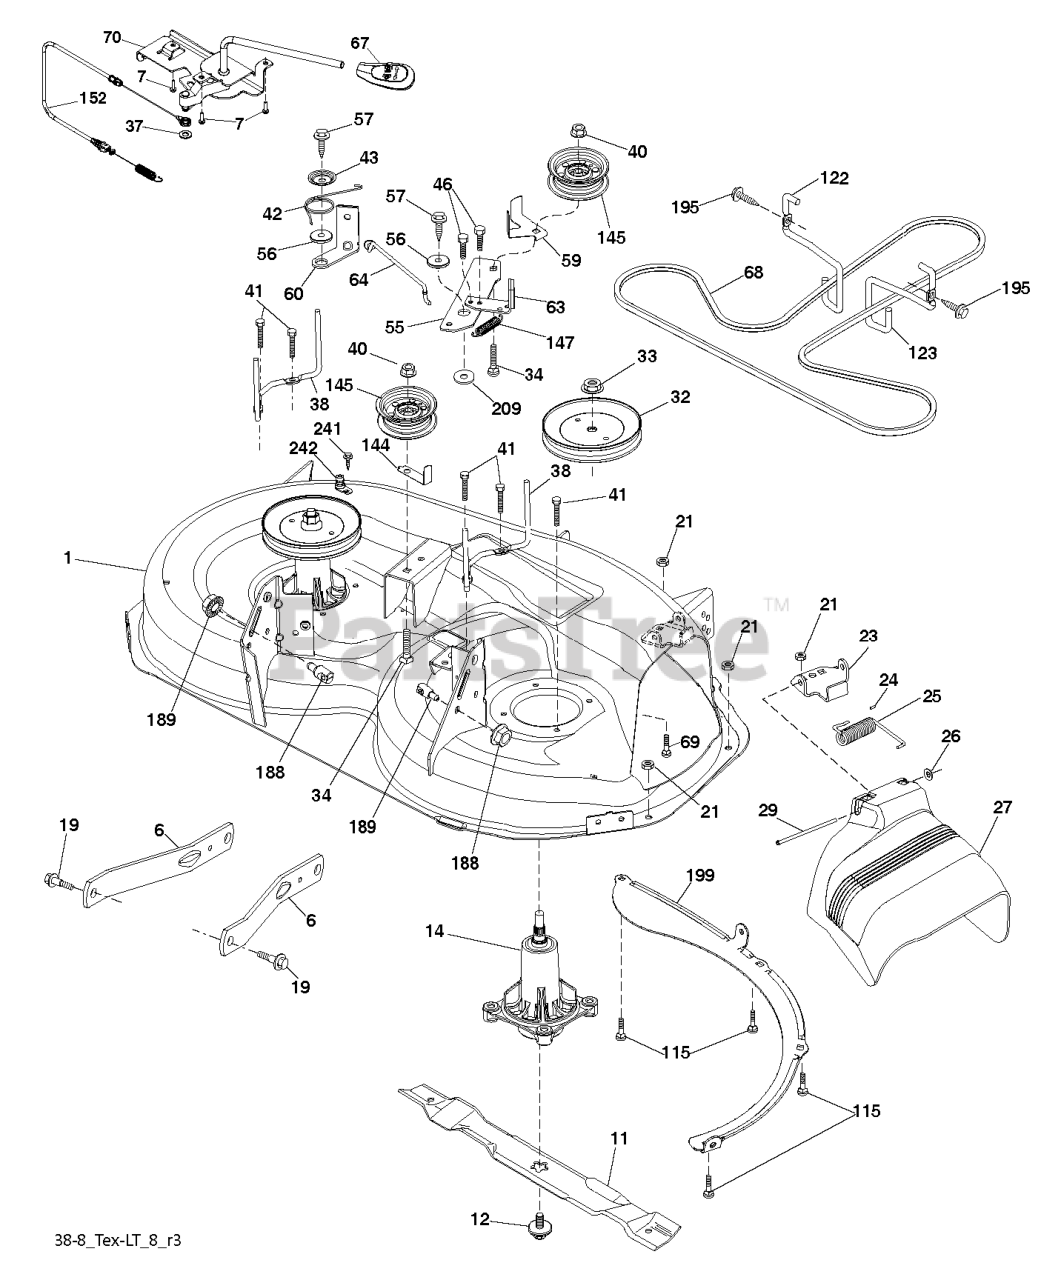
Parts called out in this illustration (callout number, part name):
6	ARM.SUSPENSION.MOWER.R
11	BLADE.2 IN 1.38"DECK
12	SCREW.SEMS.7/16-20X1.HEX.HEAD
14	KIT.MANDREL.NONGREASE.TALL
19	BOLT.SHOULDER
23	BRKT.DEFLECTOR.38"2005+
24	CAP-SLEEVE LT
25	SPRING.TORSION.DEFLECT
26	NUT PUSH M
27	SHIELD, DEFLECTOR
32	PULLEY.MANDREL.5.0.PD.38"
34	GSPW Bolts
37	WASHER
38	KEEPER BELT LH MANDREL
40	NUT LOCK FLG 3/8-16 UNC
41	BOLT.HEX.WASHR.HED.313-18X1.19
42	SPRING.TORSION.BRAKE
43	SRPING.TORSION.RETAINE
46	SCREW.1/4-20X5/8
56	SPACER.RETAINER
57	SCREW 3/8-16X1
59	GUARD, BELT
60	ARM BRAKE MOWER RH 38"
63	RP ARM.BRAKE.MOWER.38"LH.TEX
64	LINK BRAKE
67	HANDLE.CLUTCH.CABLE.LT
70	CLUTCH.ASM.MANUAL.LT.PRED
115	BOLT.CARR.5/16-18X5/8.SHORT
122	KEEPER BELT ENGINE LH
123	KEEPER BELT RH
144	KEEPER BELT
145	PULLEY.IDLER.48"PRIMARY
147	SPRING RETURN
152	CABLE.CLUTCH.MANUAL.
188	STUD.FASTNER.W/ANTI-ROTATE
195	SCREW, 3/8-16X3/4
199	BAFFLE.VORTEX.FRONT.38"
241	SCREW.TT.#10-32X.5.3/8.FLANGE
242	PORT.WASHOUT
